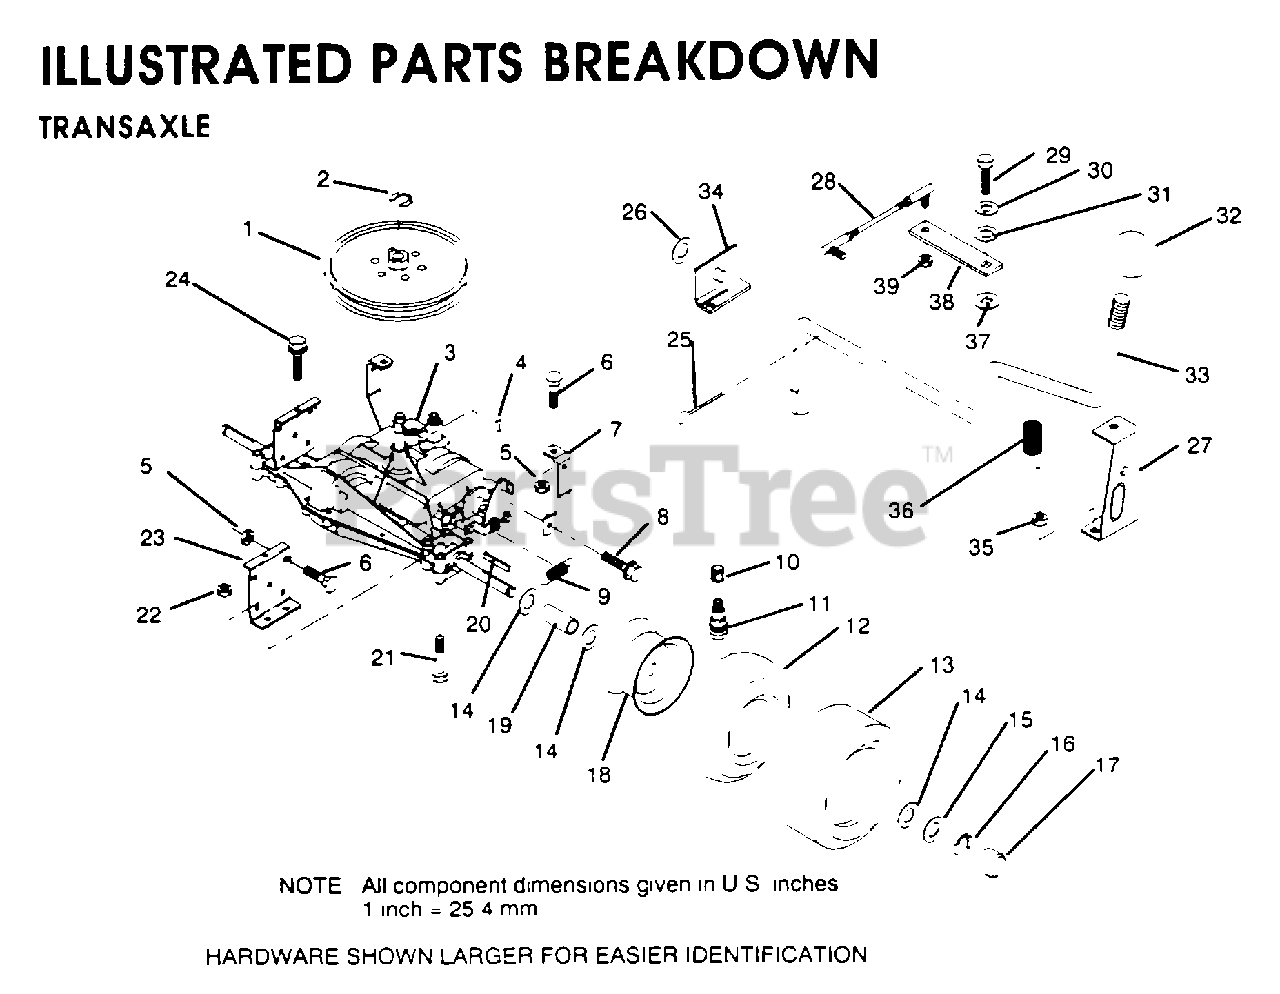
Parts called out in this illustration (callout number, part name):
1	PULLEY
6	BOLT
7	"STRAP,TORQUE"
8	SCREW LT
10	VALVE CAP
11	VALVE STEM LT
12	TUBE.16X6.5/7.5-8
14	WASHER
15	WASHER
16	E-RING LT
17	HUB CAP
19	SPACER
20	SQUARE KEY
21	BOLT
23	"BRKT,TRANSAXLE"
24	SCREW
25	PIN COTTER 1/8
27	"SUPT,HDLE RH"
28	"LINK,SHIFT"
30	LOCKWASHER
31	WASHER LT
32	KNOB T (1/2-HOLE)
33	"ROD,SHIFT"
34	"SUPT,HDLE SHT LH"
36	"SPRING,EXT"
37	WASH-SHFT PLT LT
38	ARM SHIFT
39	NUT.LOCK.5/16-24
